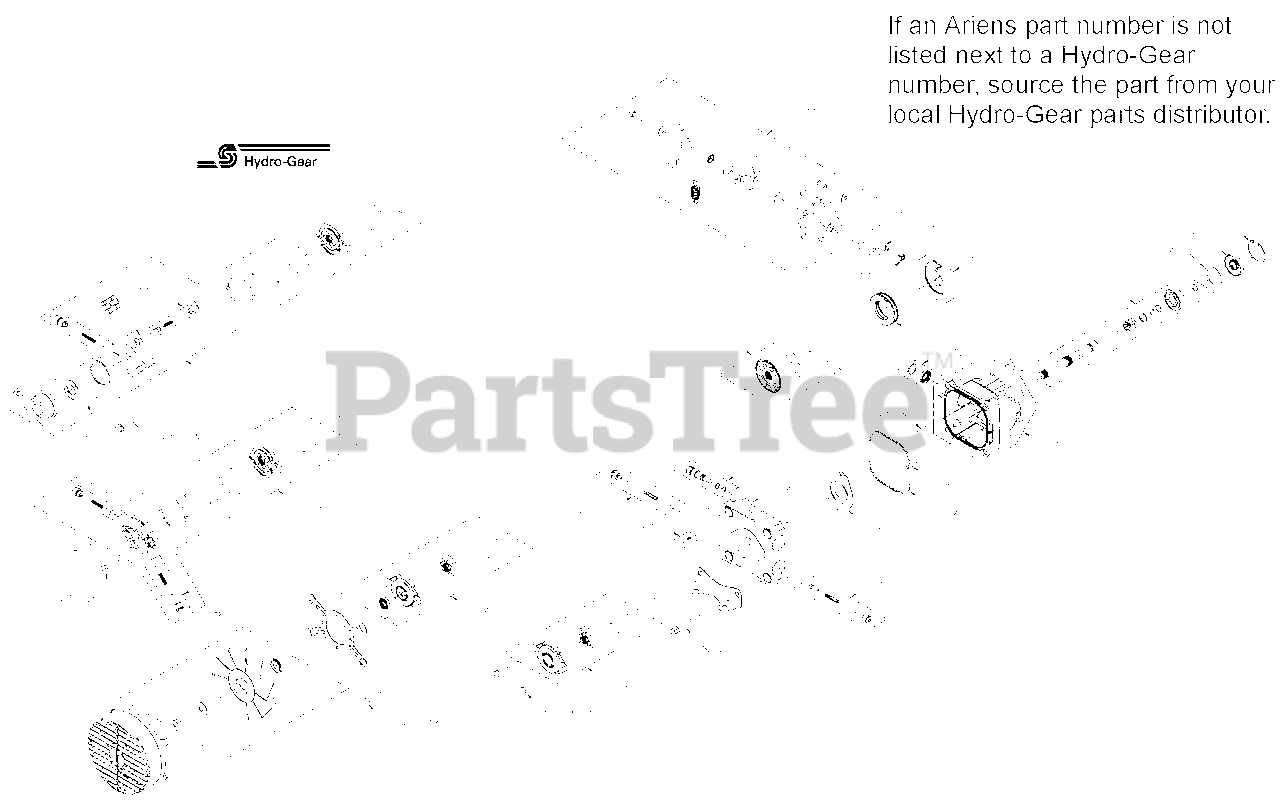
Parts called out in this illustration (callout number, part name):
1	Kit, Pump Shaft
3	Ring, Ret 47 Int
4	Washer, 1.45 x 1.84 x .04
6	Seal, Lip 17 x 47 x 8
12	Kit, Bdp-16a Trunnion Seal
13	Arm, Trunnion
14	Guide, Slot
15	Service Kit, Housing
17	Bearing, Thrust Ball 42 x 68 x 16
25	Kit, End Cap
26	Pin, .219 x 1
28	O-Ring, Square 1 x (4.3 x 4.6)
29	Valve Plate
31	Plate, Swash 21cc
38	Kit, Motor Block
42	Kit, Shock Valve 200 Bar
50	Kit, Bypass Valve
54	Kit, Auxiliary Filter
56	HFHCS 5/16-18 x 2.5
58	Kit, Bolt
110	Kit, Return
